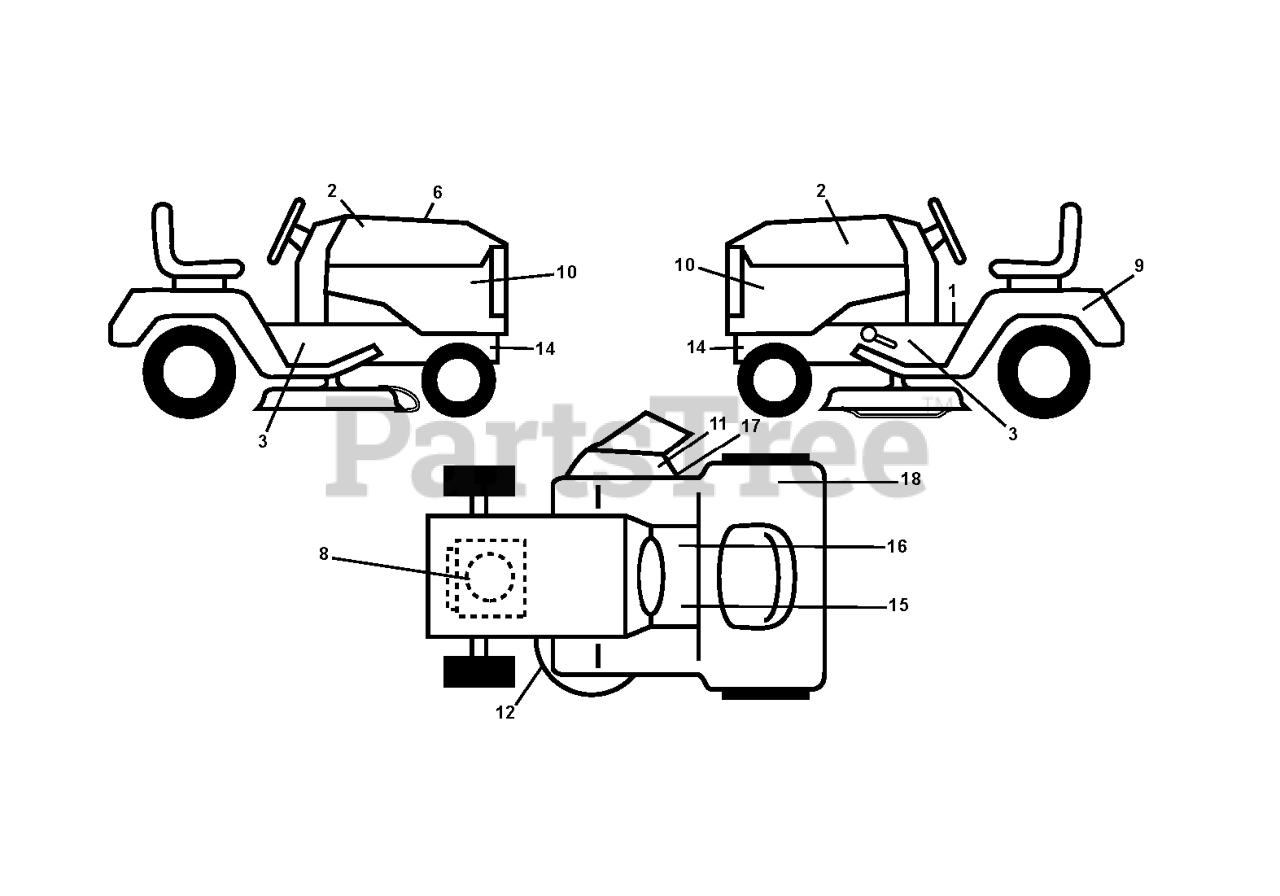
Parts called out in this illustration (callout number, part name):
1	LABEL
2	RP.DECAL.BADGE.170MM.TEXTLOGO
8	DECAL
9	DECAL BTRY SYMBOLS
10	DECAL SIDE PANEL
11	DECAL.INTERNATIONL.CUTFINGER
12	DECAL.V-BELT.SCHEMATIC.36/38/9
15	DECAL
16	DECAL PARK BRAKE
17	DECAL, DEFLECT WARNING
18	Decal, Fender 100 DB/CE
